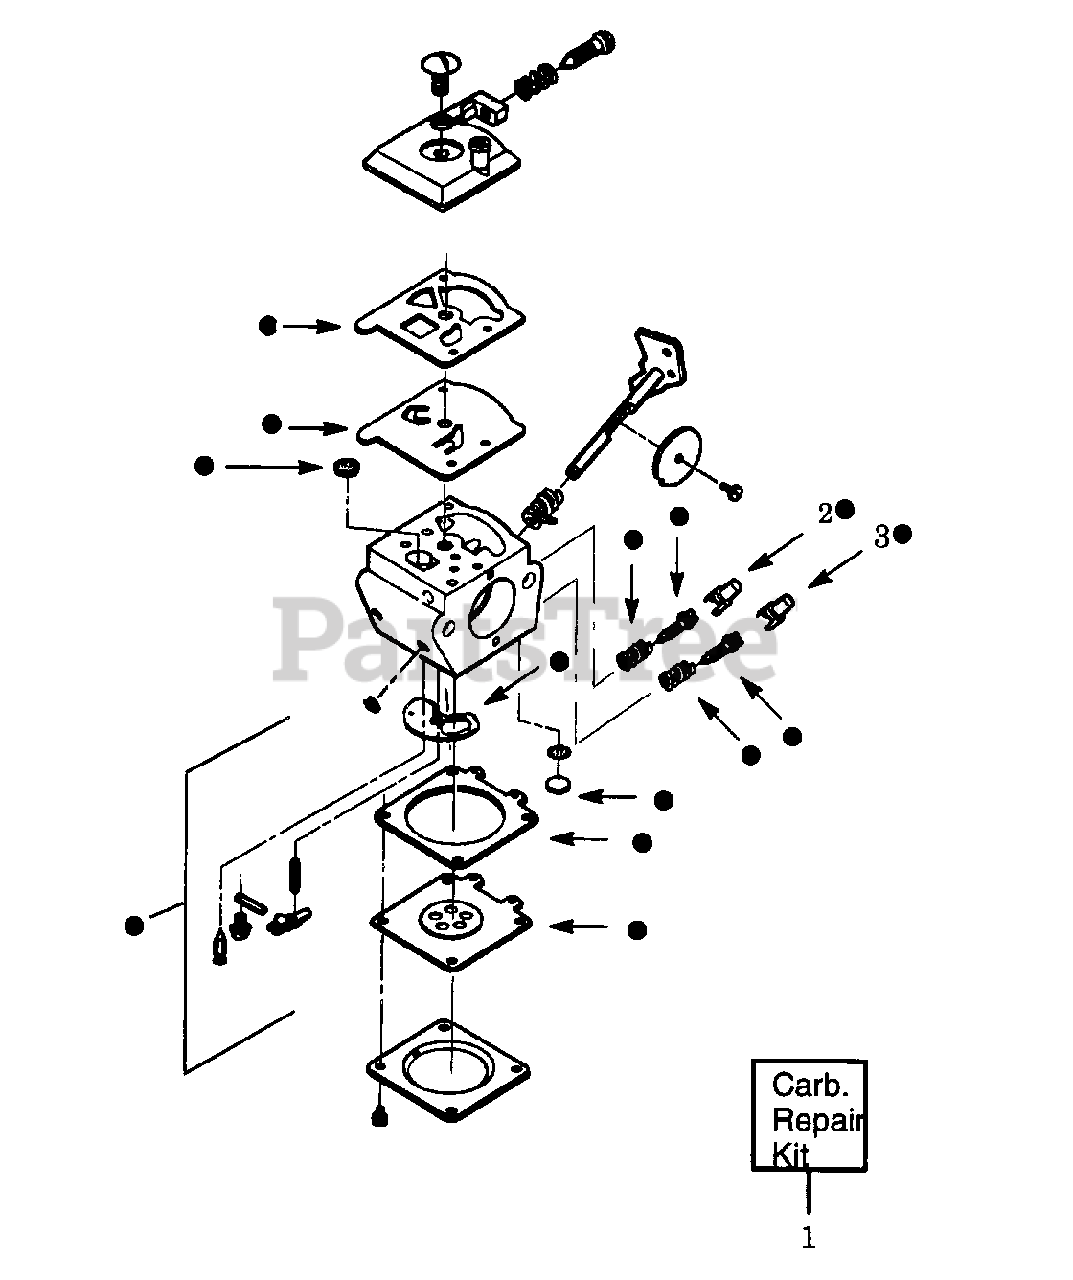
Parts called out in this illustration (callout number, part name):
1	Carburetor Repair Kit
2	Limiter Cap-Low
3	Limiter Cap-High
